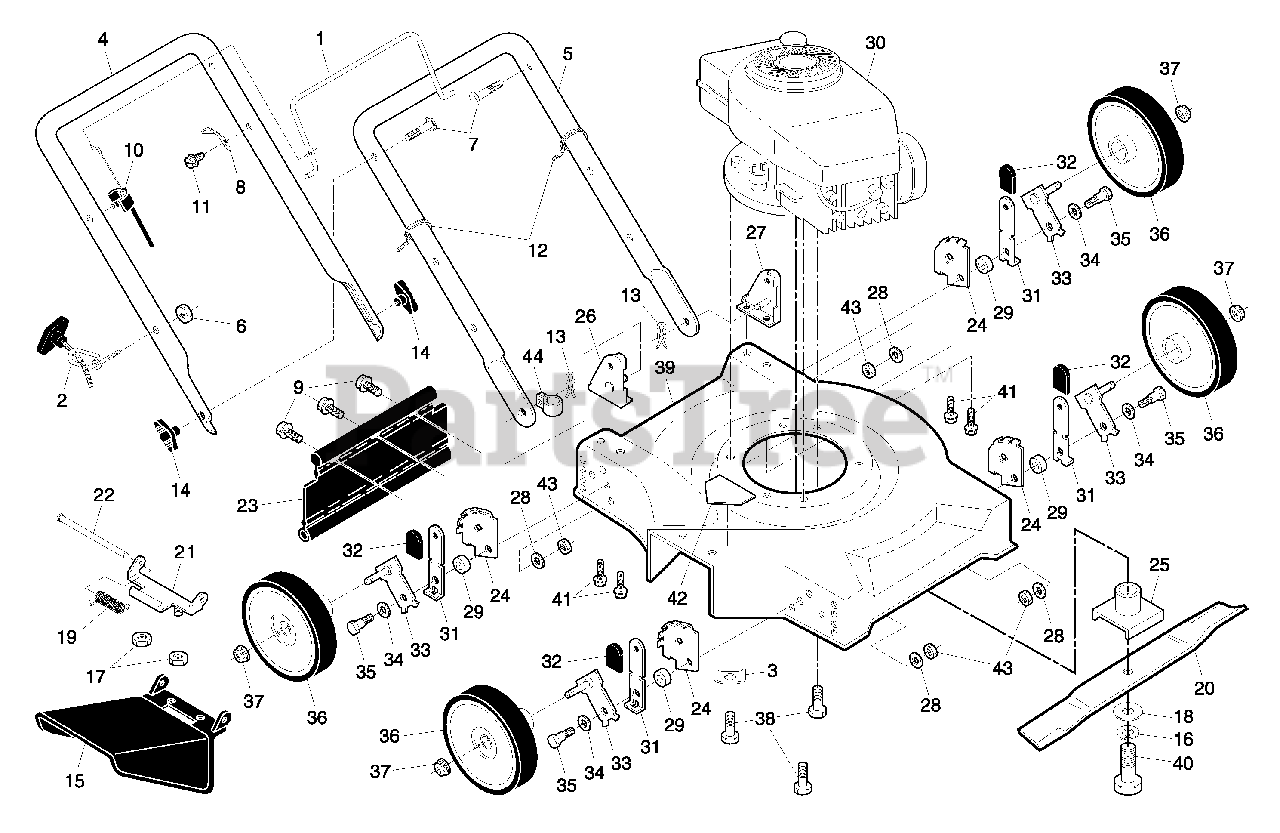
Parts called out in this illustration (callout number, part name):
1	Control Bar
2	Rope Guide
3	Washer, Engine, Zinc Plated
4	Upper Handle
5	Lower Handle
6	Nut, Hex 1/4-20
7	Bolt, Handle 5/16-18 x 1-3/4
8	Up-Stop Bracket
9	Screw, Hex Washer Head #10-24 x 1/2
10	Cable, Operator Presence
11	Screw
12	Wire Tie
13	Hairpin Cotter
14	Knob, Handle
15	Discharge Guard
16	Washer, Lock, Helical Spring 3/8
17	Locknut, Hex 1/4-20
18	Washer, Hardened
19	Spring, Torsion
20	Blade, 20"
21	Hinge Bracket
22	Hinge Rod
23	Rear Skirt
24	Bracket, Wheel Height Adjustment
25	Blade Adapter
26	Handle Bracket Assembly, RH
27	Handle Bracket Assembly, LH
29	Spacer
31	Selector Spring
32	Selector Knob
33	Axle Arm Assembly
34	Washer, Belleville
35	Bolt, Shoulder
36	Wheel & Tire Assembly
37	Nut, Hex
38	Screw, Hex Head, Threaded, Rolled 3/8-16 x 3/4
39	Housing Assembly
40	Screw, Hex Head, Grade 8, 3/8-24 x 1-3/8
41	Screw, Thread Cutting 5/16-18 x 3/4
42	Decal, Danger
43	Locknut, Hex 3/8-16
44	Clip, Cable
